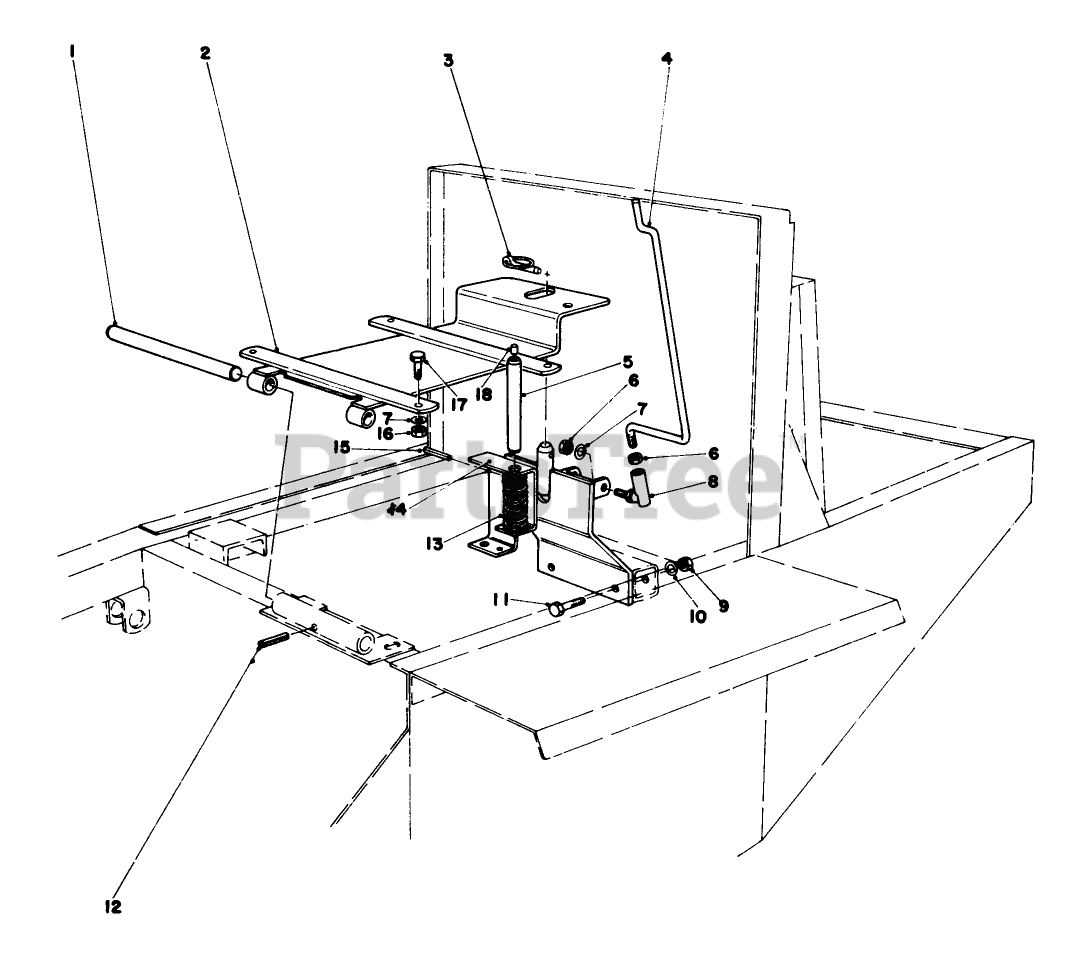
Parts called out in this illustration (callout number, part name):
1	SHAFT-PIVOT, SEAT
2	Seat Support
3	PIN-LYNCH
4	PROP SEAT
5	PIN-SWITCH, SEAT
6	NUT-JAM
7	WASHER-LOCK/SP
8	Ball Joint
9	NUT-HEX
10	WASHER-LOCK
11	SCREW-HH
12	PIN-ROLL, SLOTTED
13	SPRING-COMP
14	Bracket-Seat Support
15	PIN-ROLL, SLOTTED
16	NUT-HEX
17	SCREW-HH
18	PIN-PEDAL
